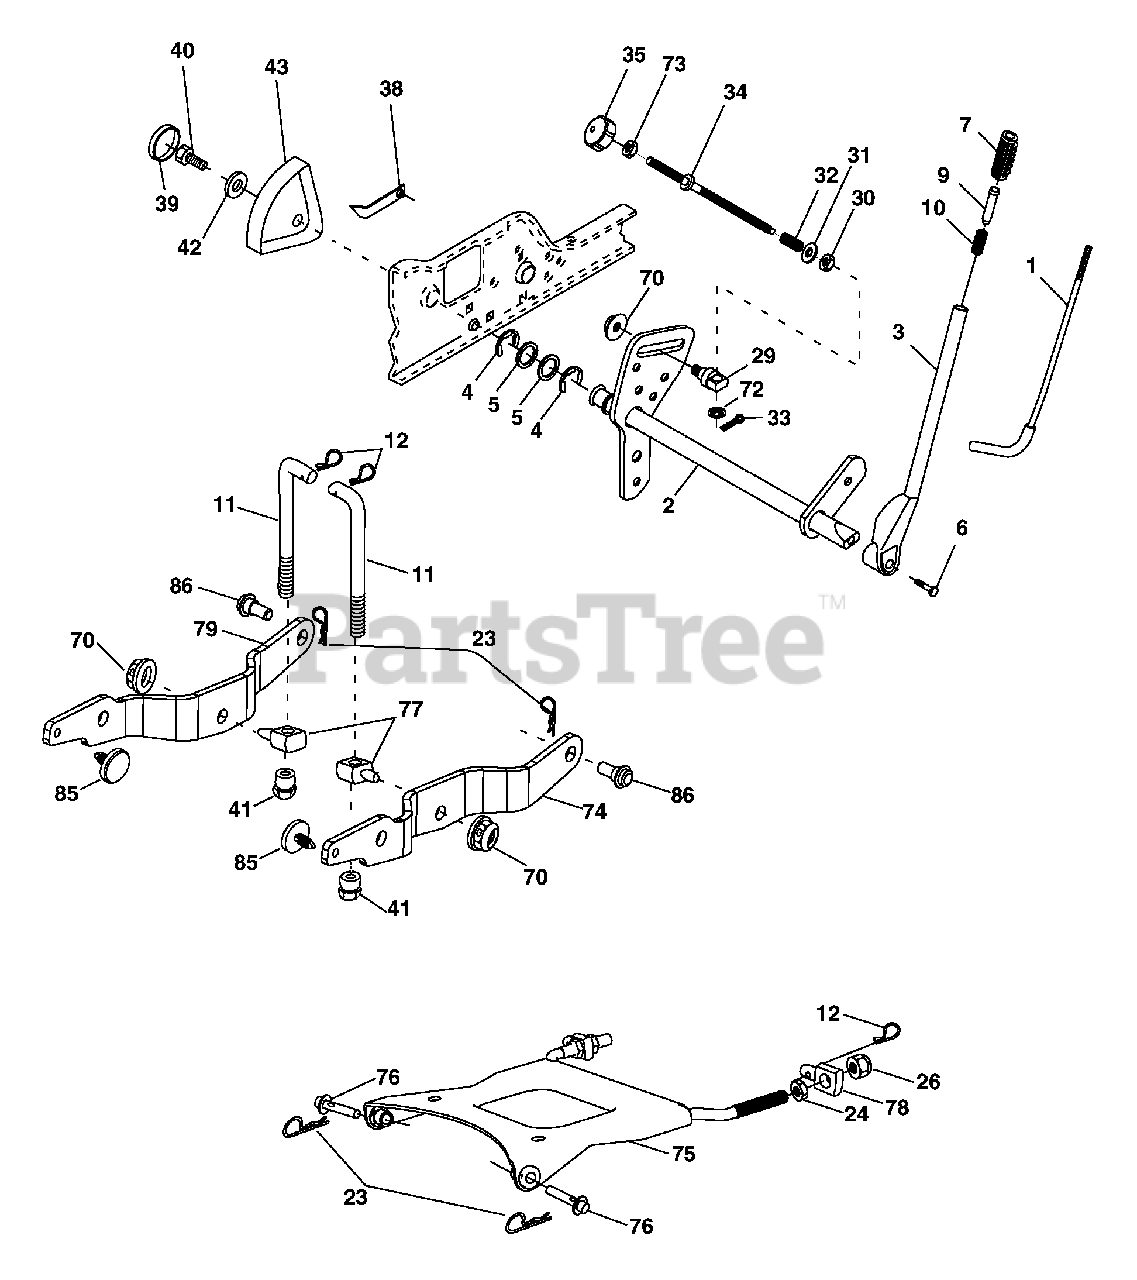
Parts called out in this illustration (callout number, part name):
1	Rod Asm., Lever
2	Shaft Asm., Lift Vgt
3	Lever Asm., Lift Rh
4	E-Ring Truarc #5133-87
5	Washer 29/32 x 1-1/4 x 16 Ga.
6	Bolt, Fin Hex 3/8-16 unc x 1-1/2
7	Grip, Handle Fluted
8	Button, Plunger
10	Spring 0.62 OD x 2.125
11	Link Lift
12	Retainer Spring
23	Retainer, Spring
24	Nut, Jam Hex 1/2-13 unc
26	Nut, Lock 1/2-13 unc
29	Trunnion, Infin Height
30	Nut, Special
31	Washer 13/32 x 5/8 x 16 Ga.
32	Spring, Compression Inf Hgt
33	Pin Cotter 3/32 x 1/2
34	Rod, Adj Lift
35	Knob, Inf 3/8-16 unc
38	Pointer, Height Indicator
39	Plug, Hole
40	Screw 5/16-18 x 1
41	Nut, 7/16-20
42	Washer 11/32 x 1-1/2 x 10 Ga.
43	Scale, Indicator Height
70	Nut Hex Flange Lock
72	Nut Push Phos & Oil
73	Nut Hex Jam 3/8-16 unc
74	Arm Susp. RH
75	Plate Asm Susp. Front
76	Pin Flange
77	Trunnion Susp. Arm
78	Trunnion Susp. Front
79	Arm Susp. LH
85	Insert Wear
86	Bolt Shoulder
